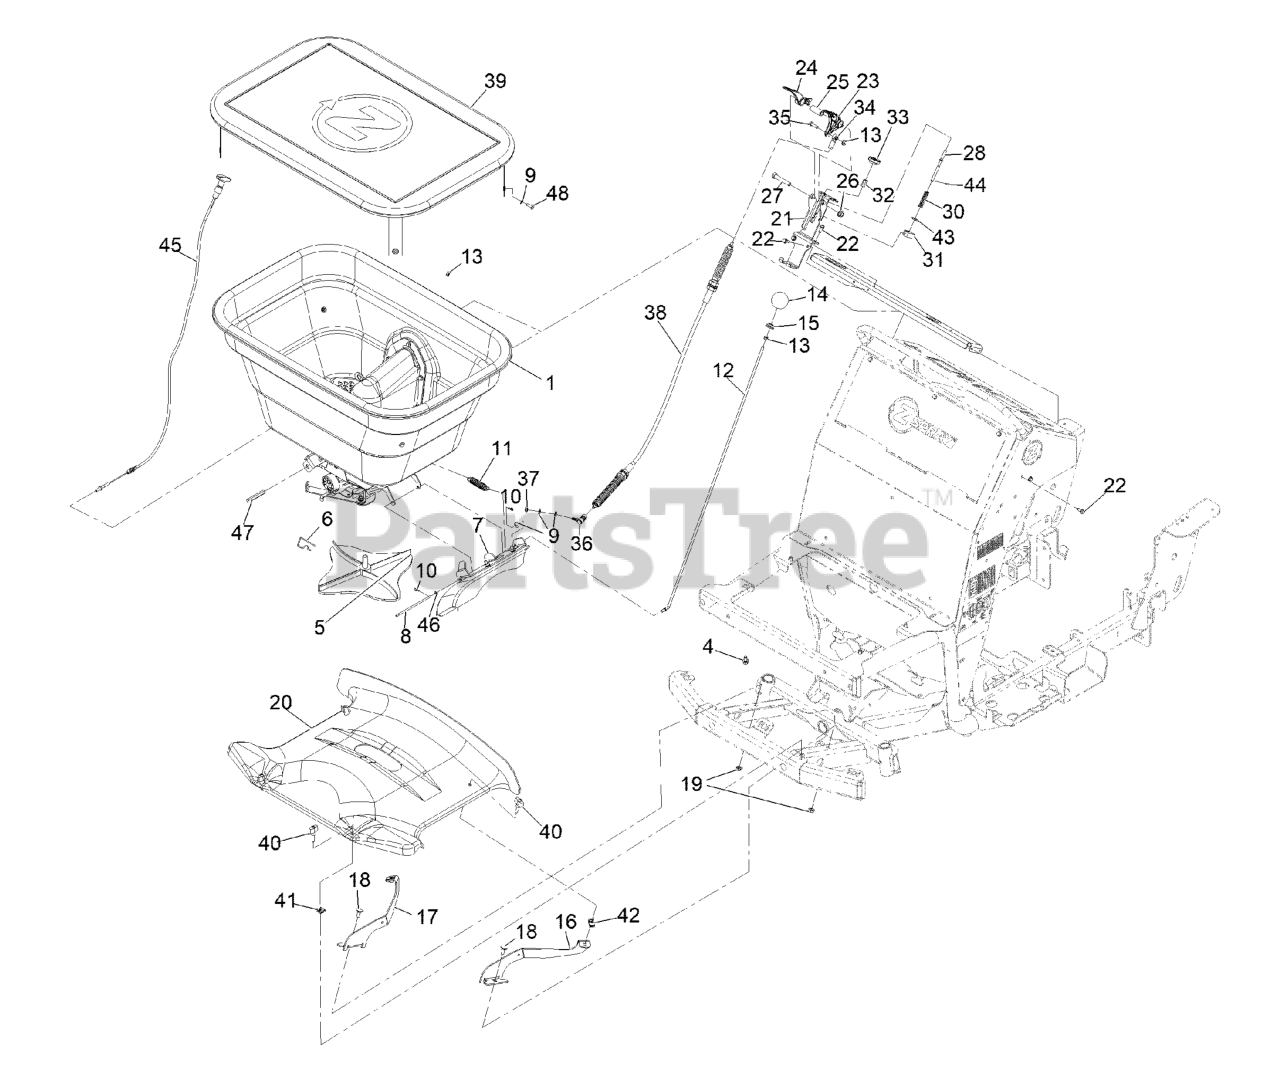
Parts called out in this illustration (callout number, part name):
1	Spreader Hopper ASM
4	SCREW-HHF
5	Spinner-Spreader
6	Clip-Spinner
7	Side Deflector ASM
8	PIN-DEFLECTOR SS
9	WASHER-FLAT
10	PIN-COTTER, HAIR
11	SPRING-EXTENSION
12	ROD-CONTROL, DEFLECTOR
14	KNOB-RATE, FLOW
15	GROMMET
16	BRACKET-COVER, FRONT (LH)
17	BRACKET-COVER, FRONT (RH)
18	SCREW-CARR
20	COVER-FRONT, SPREADER/SPR
21	MOUNT-HANDLE
22	SCREW-HWH
23	LEVER-SPREAD, WIDE
24	LEVER-SPREAD, NARROW
27	SCREW-HH
28	LINK-ADJUST, NARROW
30	SPRING-COMPRESSION, BAIL
31	STOP-SPREAD, NARROW
32	NUT-COUPLER
34	ROD END-BALL JOINT
35	SCREW-HH
36	BALL-JOINT
37	NUT-HEX, NI
39	Cover-Hopper, Clear Vinyl Window
41	NUT-RETAINER, U STYLE
42	NUT-RETAINER
43	WASHER-FLAT
44	PIN-COTTER
45	CABLE-CONTROL, TURN LOCK
46	WASHER-FLAT
47	POST-HEX, DIFFUSER GUIDE
48	SCREW-HH
